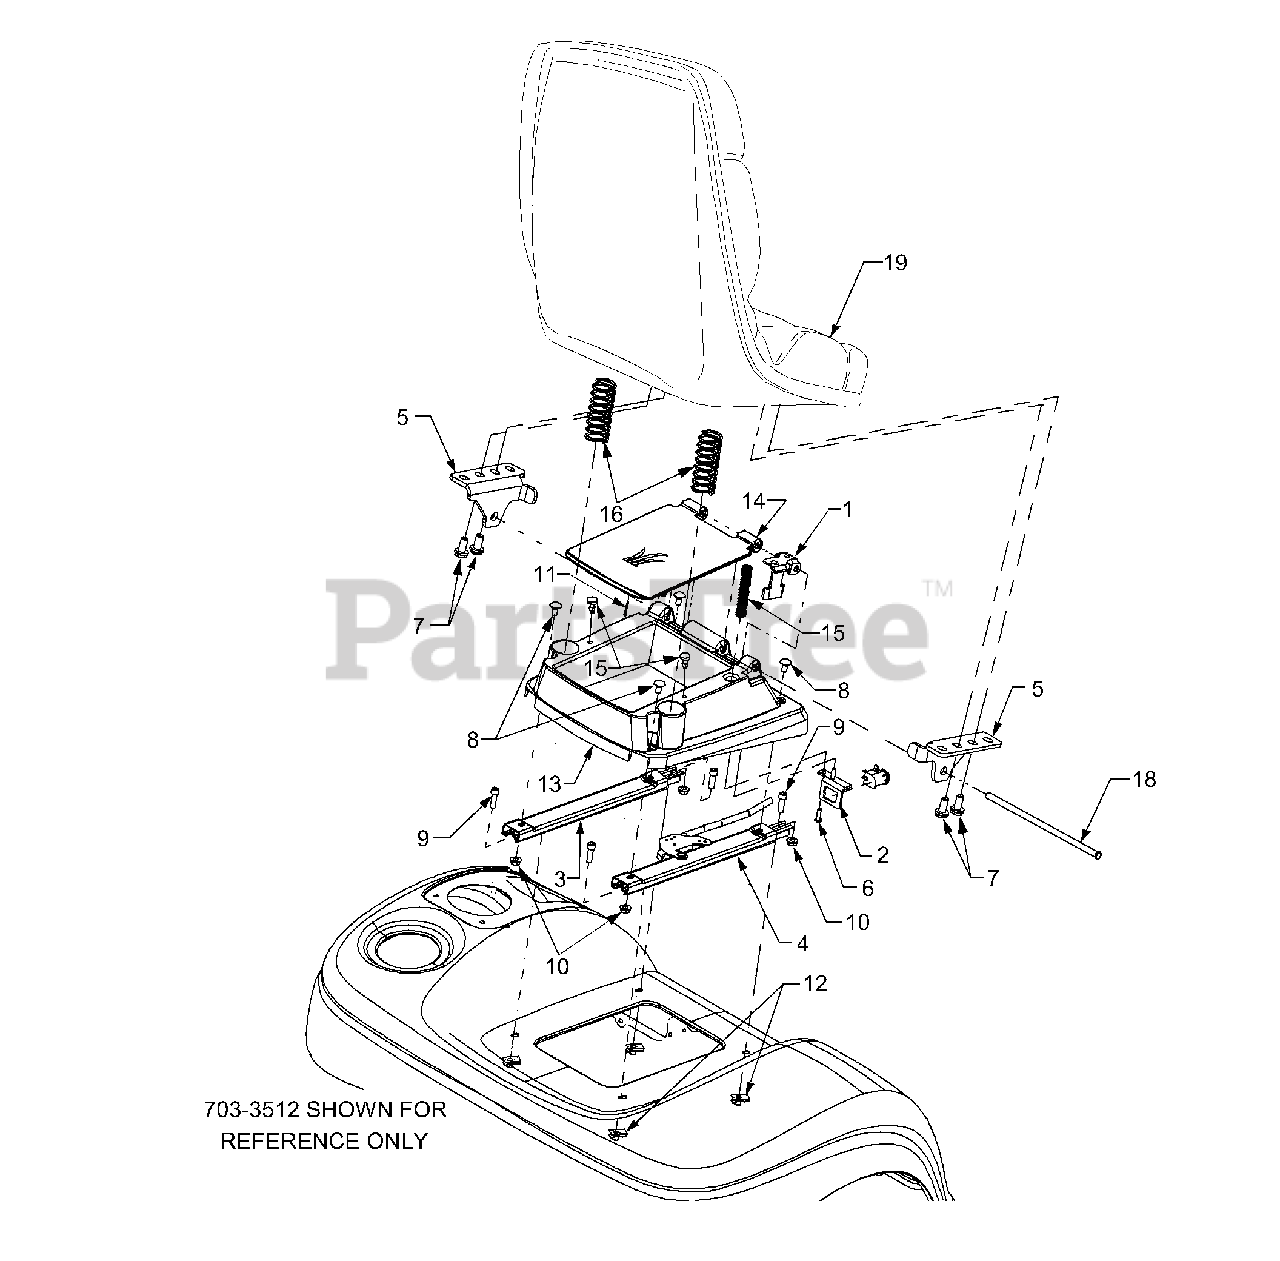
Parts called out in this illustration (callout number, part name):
1	Bracket, Seat Switch
2	Bracket, Switch Mounting
3	Track, Seat, w/o Latch
4	Track, Seat, w/Latch
7	Screw, Hex Wash. Hd 5/16-18 x .625
8	Carriage Bolt, 5/16-18 x .62
9	Screw, Pan Torx Hd 5/16-18 x 1.0
10	Nut, Hex Flange Lock, 5/16-18
11	Pin, Cotter, 3/32 x .75
12	Speed Nut, U-Type, 5/16-18
13	Base, Seat
14	Lid, Tlbx
15	Spring, Compression
16	Spring, Compression
18	Rod, Seat Pivot
19	Seat, High Back
